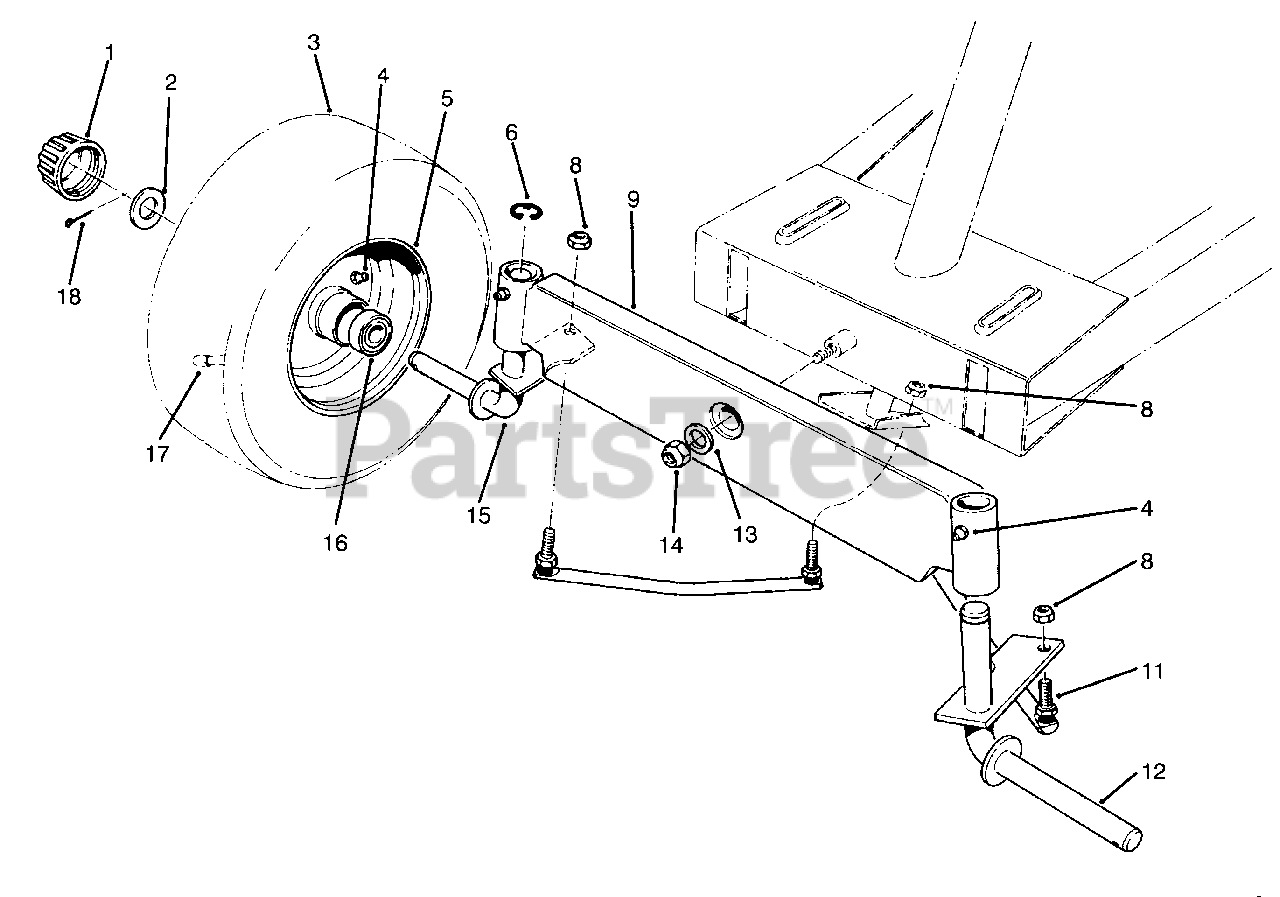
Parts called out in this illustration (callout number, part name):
2	Washer-Flat
4	Fitting-Grease
6	Ring-Retaining
8	Nut-Lock
9	Axle-Front
11	Assembly-Tie Rod
12	Spindle-L.H.
13	Washer-Flat
14	Nut-Lock
15	Spindle-R.H.
16	Bearing
17	Valve Stem w/Cap
18	Pin-Cotter
